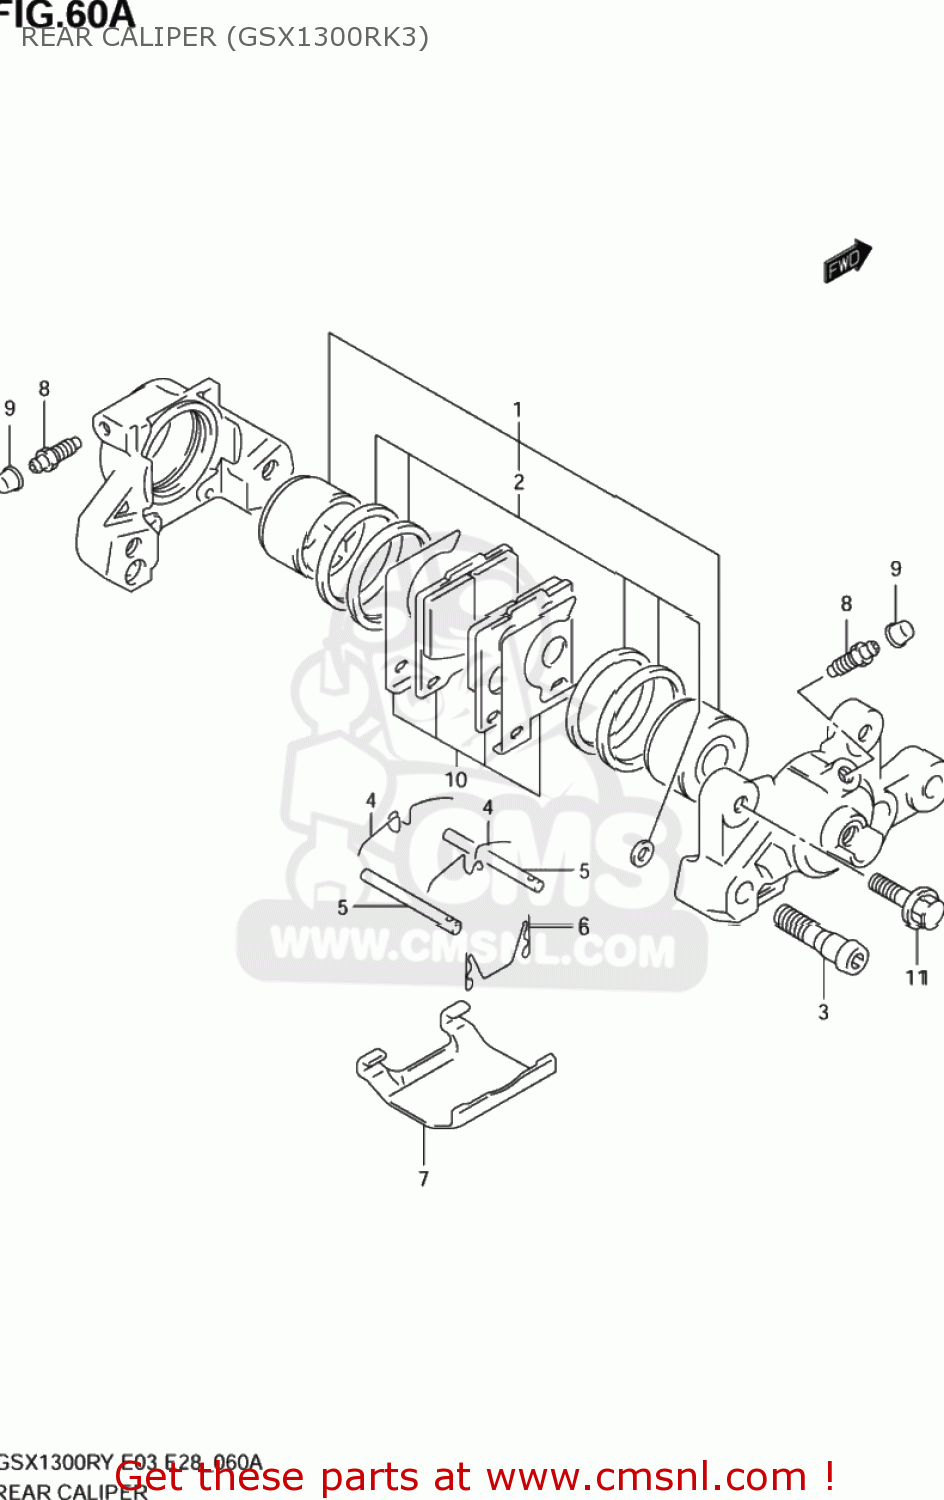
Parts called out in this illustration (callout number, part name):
1	PISTON SET
2	SEAL SET,PISTO
3	BOLT,HOUSING
4	SPRING
5	PIN,PAD
6	CLIP,PAD PIN
7	COVER
8	BLEEDER
9	CAP,BLEEDER PLUG
10	PAD & SHIM SET (NAS)
11	BOLT(8X28)
